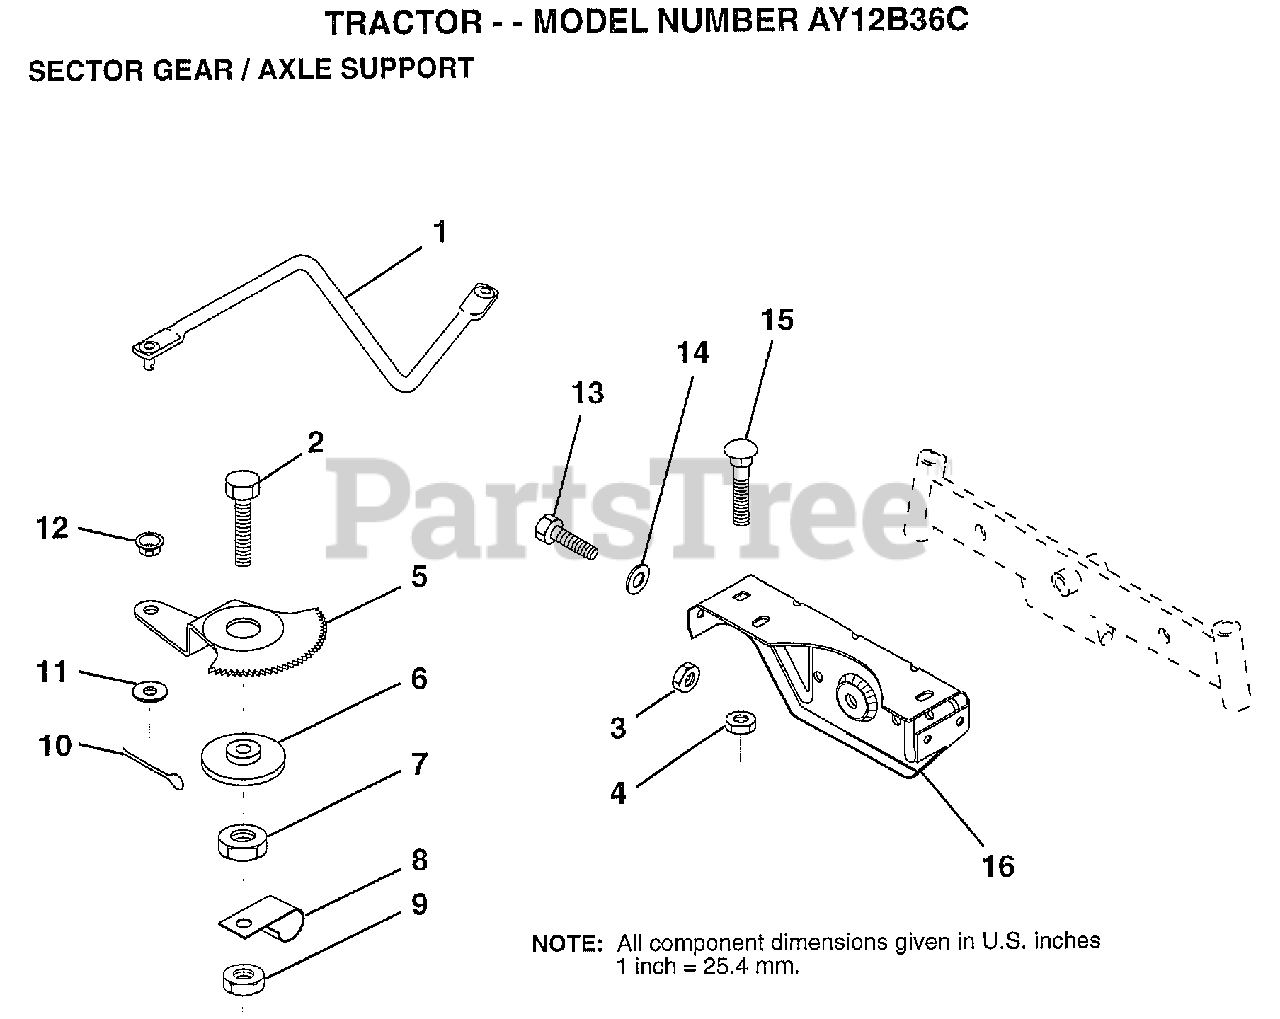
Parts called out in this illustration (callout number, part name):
1	DRAG LINK
2	"BOLT,HEX"
5	GEAR SECTOR
6	BUSHING
7	NUT
8	CLIP INSULATOR
9	NUT LTV
10	COTTER PIN
11	WASHER
12	BUSHING.DRAGLINK
13	BOLT
14	WASHER
15	BOLT
16	SUPT AXLE FRONT
